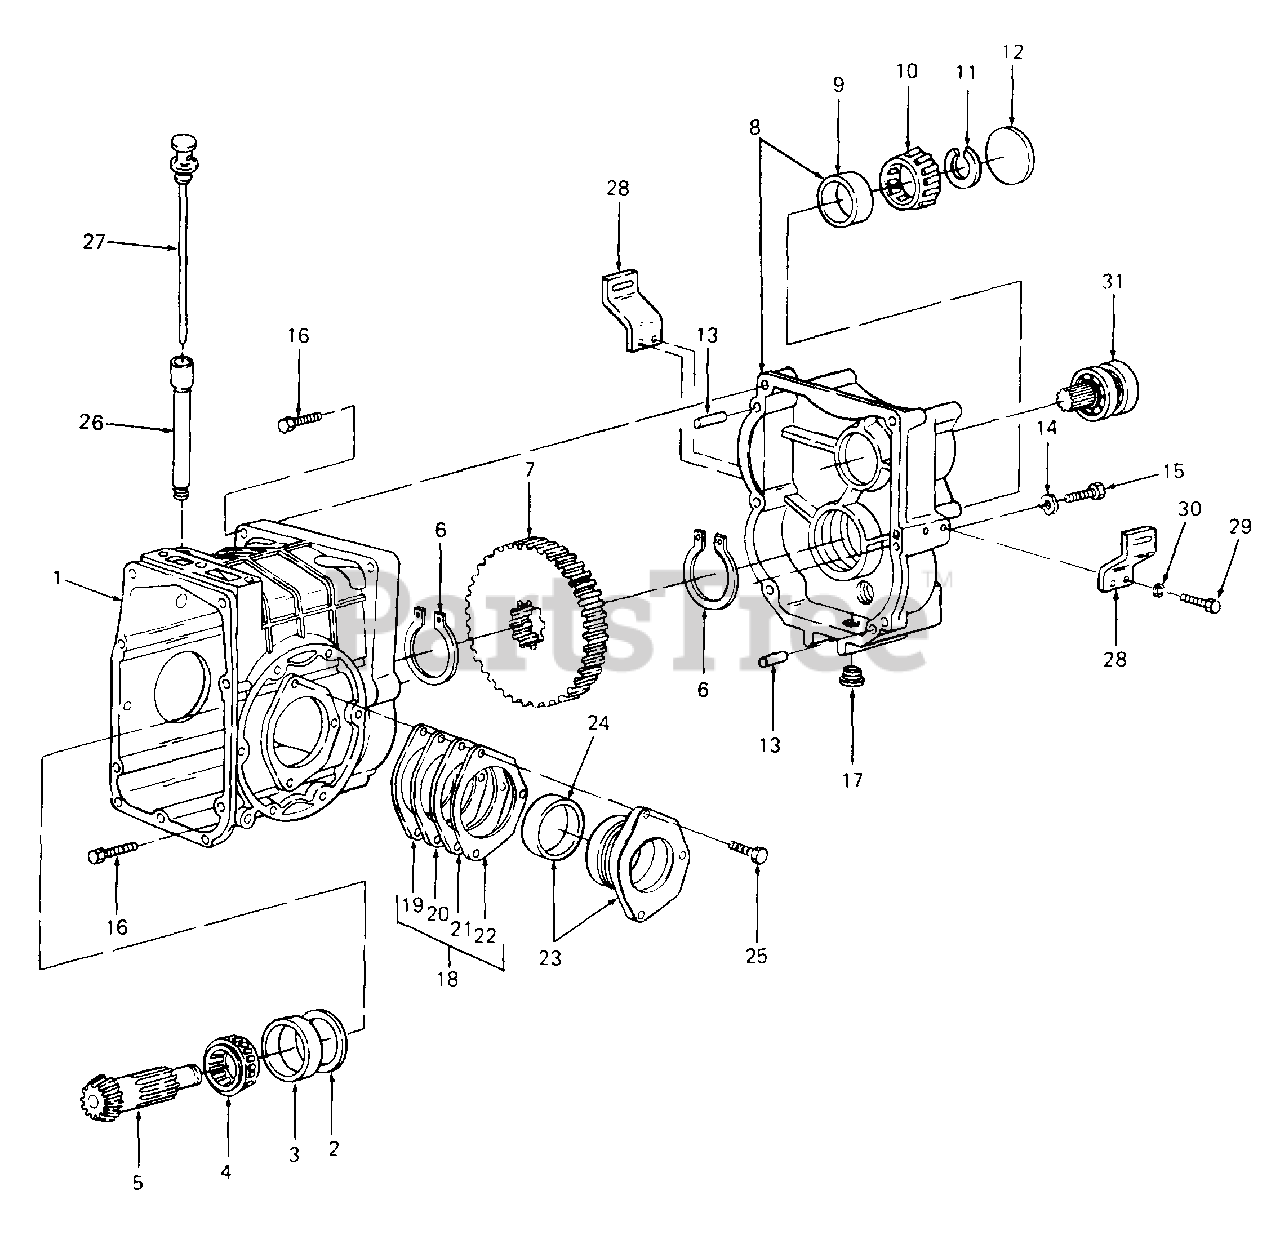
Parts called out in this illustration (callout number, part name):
1	Housing Assy, Rear Transaxle
2	Shim, Rear Bearing Cup, .004 Thk
3	Cup, Roller Bearing
4	Cone, Roller Bearing
5	Shaft, Bevel Pinion
6	Ring, Retaining, 1.312 Dia
7	Gear, Reduction - 71T
8	Housing Assy, Adapter
9	Cup, Roller Bearing
10	Cone, Roller Bearing
11	Retainer, Front Bearing, .125 Thk
12	Plug, Expansion, 2.12 OD
13	Pin, Dowel, 3/8 Dia X 5/8 Lg
14	Washer, Spring, .445 X .75 X .017 Thk
15	Screw, Hex Cap, 7/16-14 X 2.75 Lg GR5
16	Bolt, Hex Patch, 7/16-14 X 1.75 Lg GR5
17	Plug, Drain
18	Shim Package
19	Shim, Bearing Retainer, .004 Thk
20	Shim, Bearing Retainer, .007 Thk
21	Shim, Bearing Retainer, .014 Thk
22	Shim, Bearing Retainer, .028 Thk
23	Retainer Assy, Bearing
24	Cup, Roller Bearing
25	Bolt, Hex Patch, 3/8-16 X 1.0 Lg GR5
26	Tube, Dipstick
27	Blade Assy, Dipstick
29	Screw, Hex Cap, 3/8-16 X 1.0 Lg GR5
30	Washer, Lock, 3/8
31	Pinion Assy, Input
